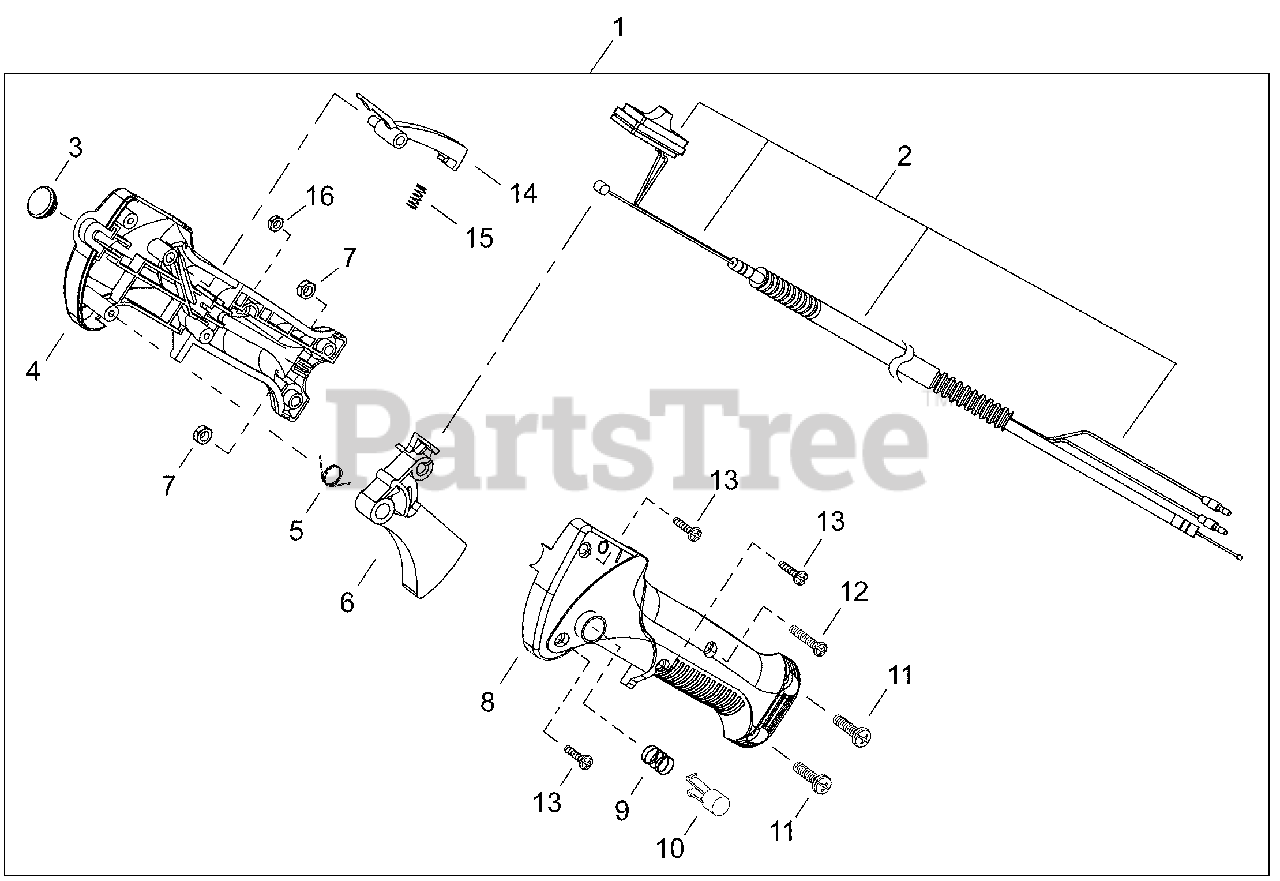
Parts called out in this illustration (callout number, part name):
1	THROTTLE CONTROL ASSY
2	CABLE ASSY, CONTROL
3	PLUG, RUBBER
4	CONTROL HANDLE - RIGHT
5	SPRING, TORSION
6	TRIGGER, THROTTLE
7	NUT M5
8	CONTROL HANDLE - LEFT
9	SPRING, COMPRESSION
10	BUTTON, THROTTLE LOCK
11	SCREW M5×20
12	SCREW M4×23
13	SCREW, TAPPING 4×16
14	LOCKOUT, THROTTLE
15	SPRING, COMPRESSION
16	NUT M4
